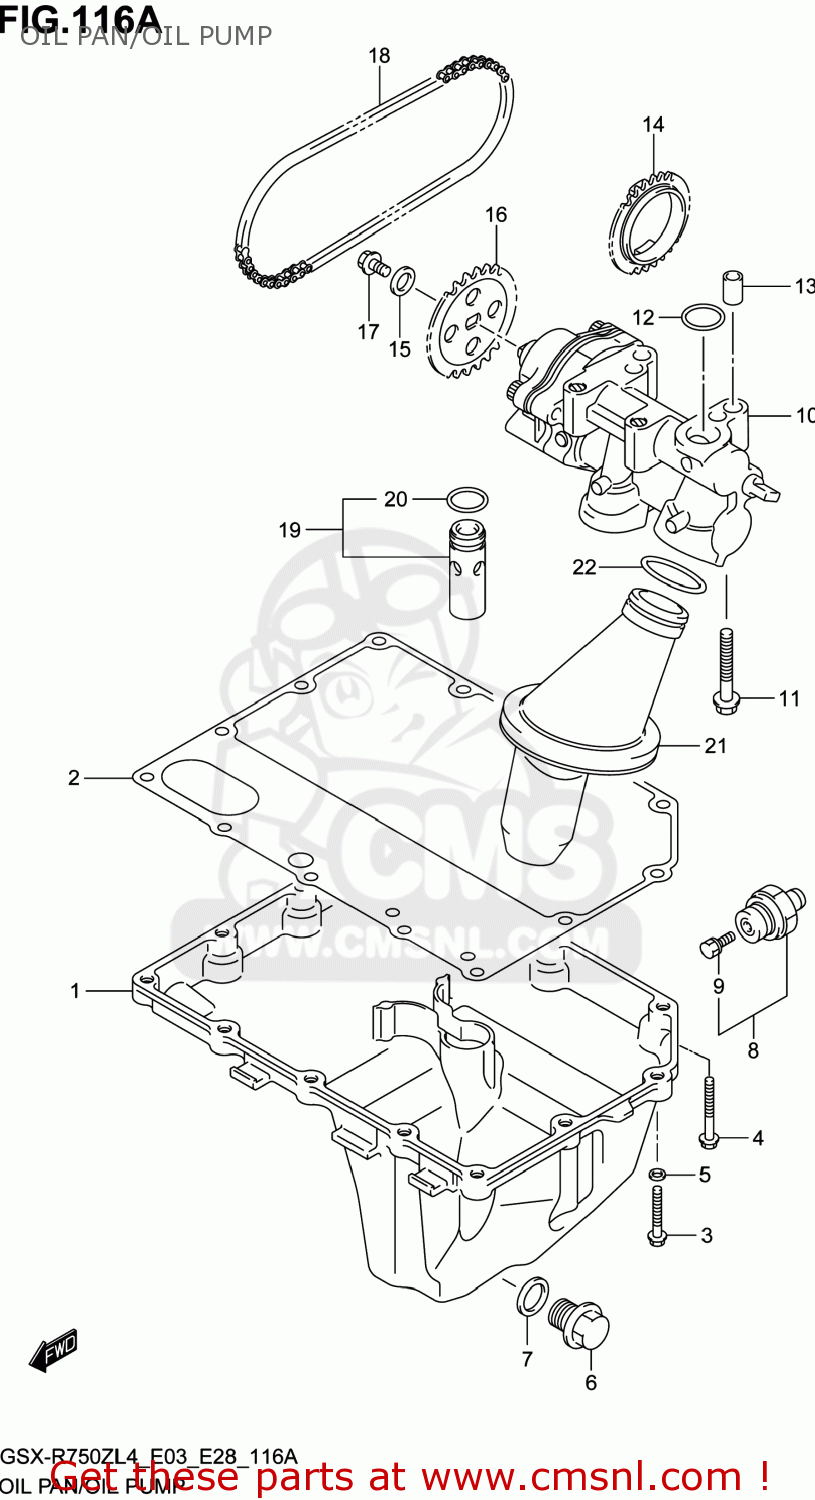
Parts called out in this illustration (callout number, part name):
1	PAN,OIL
2	GASKET,OIL PAN(ASB) (NAS)
3	BOLT
4	BOLT(6X30)
5	GASKET(5.8X13X1.2) (NAS)
6	PLUG(14X20)
7	GASKET(13.8X18.8X4.8) (NAS)
8	SWITCH ASSY,OIL PRESSURE
9	BOLT,OIL PRESSURE SWITCH
10	PUMP ASSY,ENGINE OIL
11	BOLT
12	O RING(D:2.4,ID:15.8)
13	PIN
14	SPROCKET,OIL PUMP DRIVE
15	SHIM(10X18X0.5)
16	SPROCKET,OIL PUMP DRIVEN
17	BOLT(6X12)
18	CHAIN,OIL PUMP DRIVE
19	VALVE ASSY,OIL RELIEF(7K)
20	O RING(D:1.9,ID:13)
21	STRAINER ASSY,ENGINE OIL
22	O RING(D:2.4,ID:24.7)
